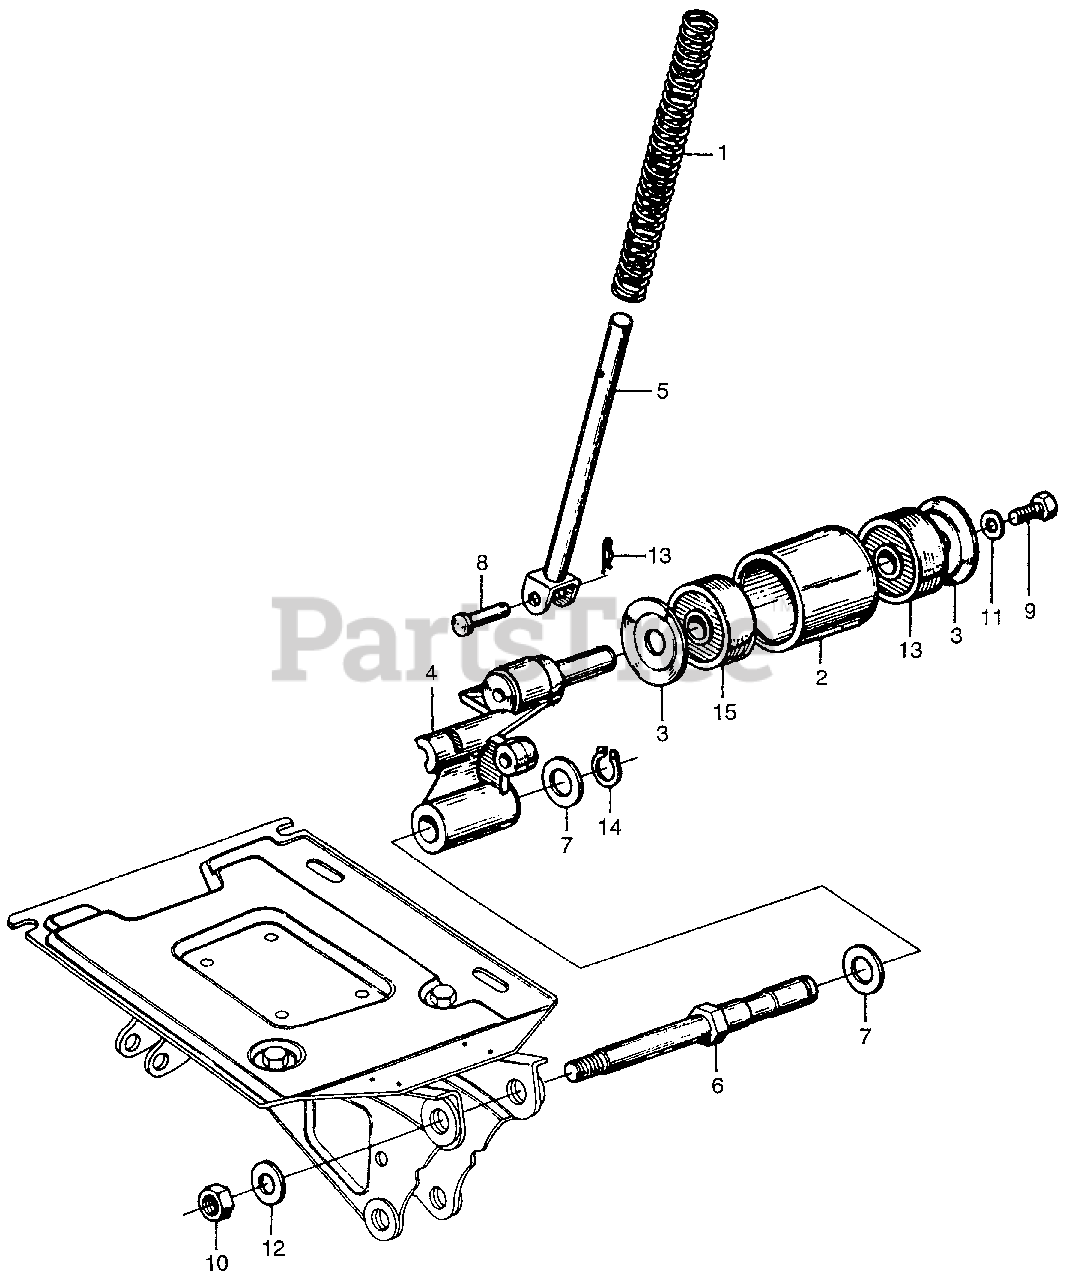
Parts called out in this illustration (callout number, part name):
1	SPRING, BELT CLUTCH (NOT AVAILABLE)
2	PULLEY, TENSION
3	COVER A, DUST
4	ARM, TENSION
6	PIN, TENSION ARM
7	WASHER, TENSIONER ARM (NOT AVAILABLE)
8	PIN, PUSH BAR (NOT AVAILABLE)
9	BOLT, HEX. (6X12)
10	NUT, HEX. (10MM)
11	WASHER, PLAIN (6MM)
12	WASHER, PLAIN (10MM)
13	PIN, LOCK (6MM)
14	CIRCLIP (OUTER) (12MM)
15	BEARING, RADIAL BALL (6200ZZ) (NOT AVAILABLE)
